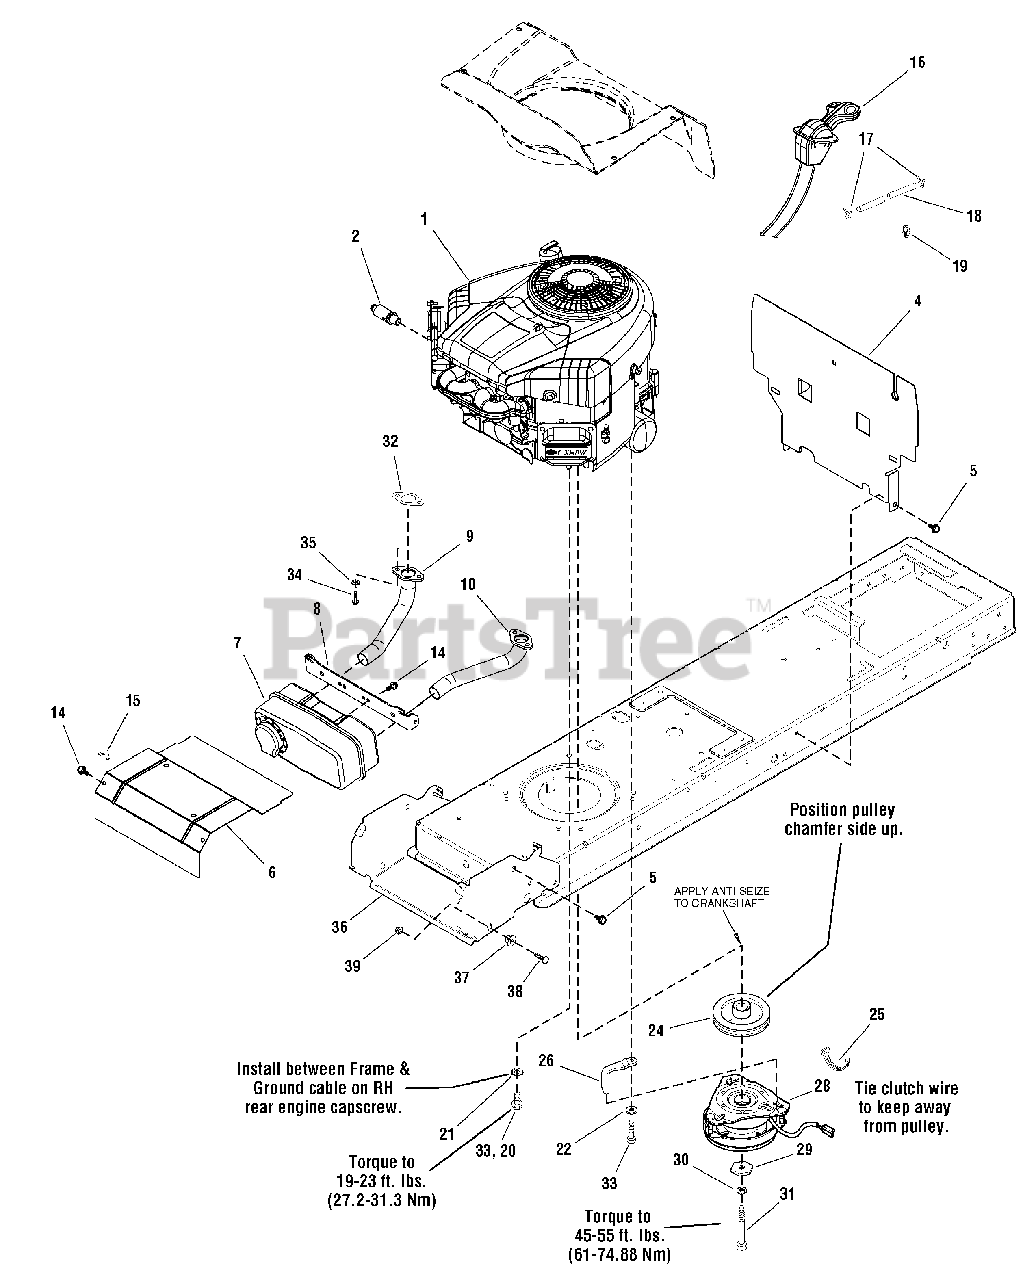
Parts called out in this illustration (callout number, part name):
1	* ENGINE, 23HP Briggs & Stratton Professional Series
1	* ENGINE, 24HP Briggs & Stratton Professional Series
2	VALVE, Shut Off Oil Drain
4	SHIELD, Heat
5	CAPSCREW, Hex Washer Head Taptite 5/16-18 x 5/8
6	SHIELD, Heat
7	MUFFLER
8	BRACKET, Muffler Mount
9	PIPE, Exhaust R.H.
10	PIPE, Exhaust L.H.
14	CAPSCREW, Hex Washer Head Taptite 1/4-20 x 1/2
15	CLIP, Speed Wire
16	CONTROL, Throttle, Choke-A-Matic
17	CLAMP, Hose
18	HOSE, Fuel
19	CLIP, Hose
20	CAPSCREW, Hex Washer Head Taptite 3/8-16 x 1
21	LOCKWASHER, External Tooth 3/8
22	WASHER, 3/8
24	PULLEY & HUB ASSEMBLY, Engine
25	TIE, Self Locking
26	RETAINER, Clutch
28	CLUTCH, Electric OGURA
29	WASHER, Hex
30	LOCKWASHER, Spring
31	CAPSCREW, Hex Head 7/16-20 x 3-1/2 G5
32	GASKET, Exhaust
33	CAPSCREW, Hex Washer Head Taptite 3/8-16 x 1-1/4
34	CAPSCREW, Hex Socket Head 5/16-18 x 3/4 G8
35	LOCKWASHER, Spring 5/16
36	SUPPORT, Muffler Hood
37	PIVOT, Hood
38	BOLT, Carriage, 5/16-18 x 1
39	NUT, Hex Flange, 5/16-18
